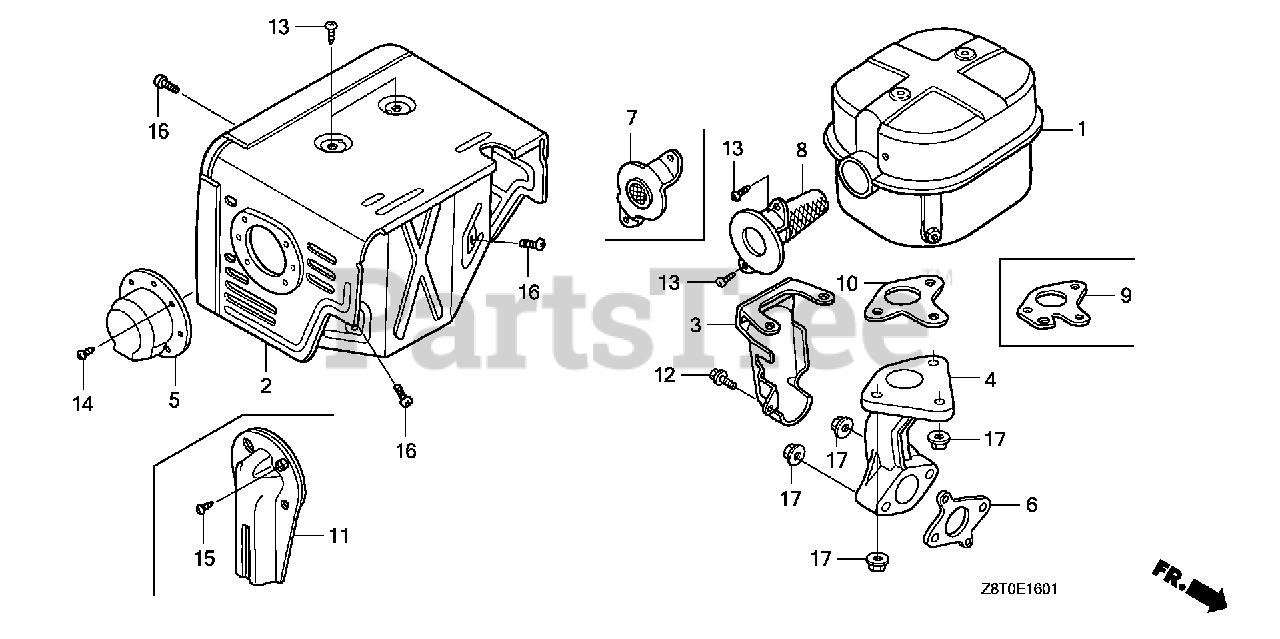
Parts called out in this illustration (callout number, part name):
1	MUFFLER
2	PROTECTOR, MUFFLER
6	GASKET, EX. PIPE
8	ARRESTER, SPARK
9	GASKET, MUFFLER (ARRESTER) (NIPPON LEAKLESS)
9	GASKET, MUFFLER (ARRESTER)(THAI LEAKLESS)
13	SCREW, TAPPING (5X8)
16	SCREW, PAN (6X6)
17	NUT, FLANGE (8MM)
